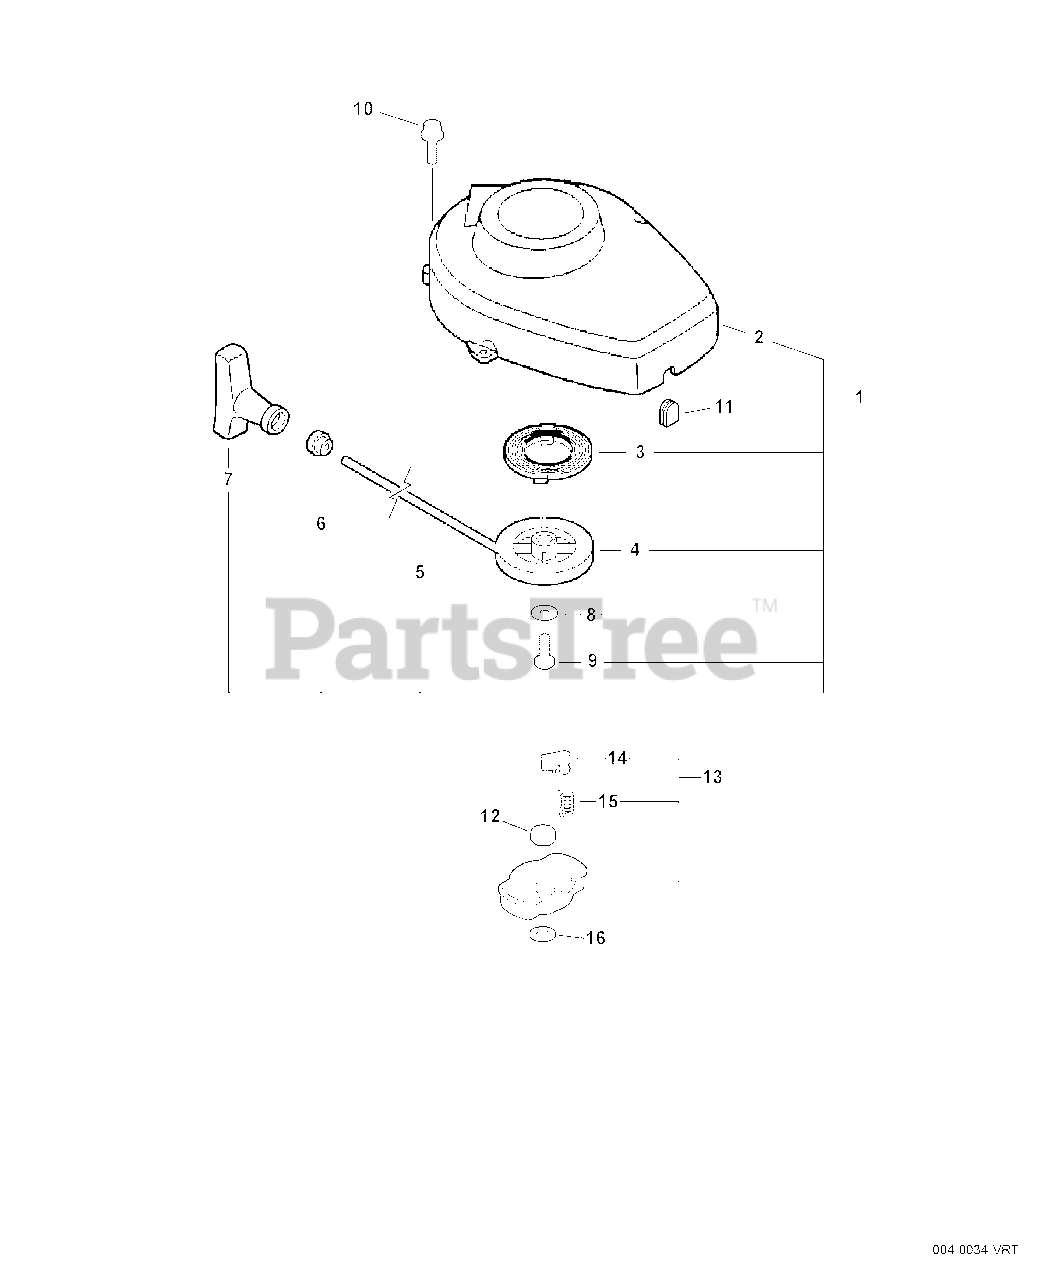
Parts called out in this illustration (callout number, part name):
1	STARTER ASSY
2	CASE, STARTER
3	SPRING, RECOIL
4	REEL, ROPE
5	ROPE, STARTER
6	GUIDE, ROPE
7	GRIP, STARTER
8	WASHER
9	SCREW
10	BOLT 4×16
11	PLUG
13	PAWL ASSY, STARTER
14	PAWL, STARTER - BLACK
15	SPRING, RETURN
16	WASHER 8.5×16×1.2
